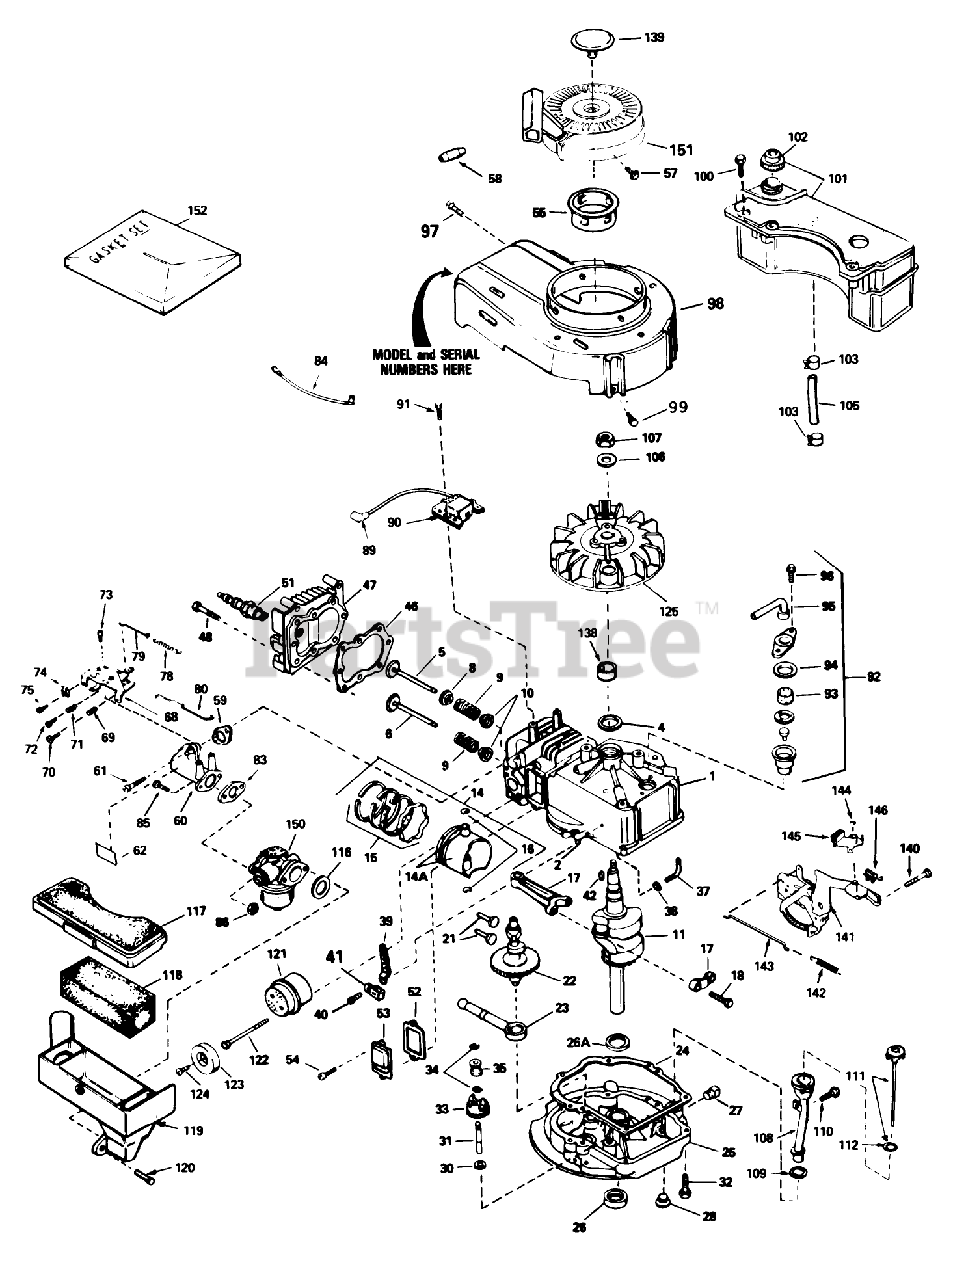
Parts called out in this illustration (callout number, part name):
1	Cylinder Assy. (Incl. #24)
2	Pin-Dowel
4	Seal-Oil
5	Valve, Intake (Std.) (Incl. Ref. #40)
5	Valve, Intake (1/32" oversize)(Incl. No. 40)
6	Valve, Exhaust (Std.)(Incl. No. 40)
6	Valve, Intake (1/32" oversize)(Incl. No. 40)
8	Seal Assy., Intake
9	Spring-Valve
10	Cap-Valve, Spring
11	Crankshaft
14	Piston, Pin Ring Assy. (Std.) (Incl. Ref. #13A, 14 15)
14	Piston, Pin Ring Assy. (.010 oversize) (Incl. Ref. #13A, 14 15)
14	Piston, Pin Ring Assy. (.020 oversize) (Incl. Ref. #13A, 14 15)
14A	Piston Pin Assy. (Incl . Ref. . #14) (Std.)
14A	Piston Pin Assy. (Incl. Ref. #14) (.010 Oversize)
14A	Piston Pin Assy. (.020 oversize) (Incl. Ref. #14)
15	Ring Set (Std.)
15	Ring Set (.020" OS)
15	Ring Set (.010" OS)
16	Ring-Retaining, Piston Pin
17	Rod Assy., Connecting (Incl. Ref. #17)
18	Bolt-Rod, Connecting
21	Lifter-Valve
22	Camshaft(Mech.Comp. Release)
23	Oil Pump ASM
24	Gasket
25	Flange-Mounting (Incl. Ref. #26, 27 39)
26	Seal-Oil
26A	Washer-Thrust
28	Plug Oil Drain
30	Washer-Flat
31	Shaft-Governor
32	Screw (1/4-20 x 1-1/4)
33	Governor Gear ASM
34	Ring-Retaining
35	Spool-Governor
37	Rod, Governor (Incl. No. 36)
38	Washer-Flat
39	Governor Lever
40	Screw
41	Clamp-Lever, Governor
42	Key-Flywheel
46	63573 GIL 42 SNWTHW
47	Head-Cylinder
48	Screw (5/16-18x1-1/2)
51	Plug, Spark (Autolite 458, Champion J-19LM or equiv.)
52	Gasket-Breather
53	Cover-Valve
54	Screw
55	Hub-Starter
57	Screw, Hex Hd.
58	Retainer-Starter Rope
59	Gasket-Intake
60	Pipe-Intake (Incl. Ref. #59)
61	Screw (1/4-20 x 1)
62	Decal-Primer
68	Control Assy.-Remote Speed (Incl. Ref. #69 thru 72 76)
69	61709/GIL1515A/95-5
70	Screw
71	Spring-Compression
72	Screw
73	Screw (10-24 x 9/16)
74	Conduit
75	Screw (10-32 x 3/8)
78	Spring Governor
79	2035A67 ADD.ASSEMBL
80	Link-Throttle
83	Gasket
84	Ground Wire
86	Nut and Lock Washer (1/4-28)
89	Cover-Spark Plug
90	Solid State
91	Screw
92	Breather Assy. (Incl. Ref. #46 thru 51)
93	Element-Breather
94	Gasket-Breather
95	Tube, Breaker
96	Screw (10-24 x 9/16)
97	Screw (10-24 x 9/16)
98	Housing-Blower
99	Screw (1/4-20 x 1/2)
100	Screw (10-32 x 35/64)
101	Tank Assembly-Fuel (Incl. Ref. #102)
102	Cap-Fuel
103	Clamp-Line, Fuel
105	Line-Fuel
106	Washer-Belleville
107	Nut-Flywheel
108	Tube-Oil Fill
109	Gasket
110	Screw (10-32 x 1/2)
111	Dipstick-Oil (Incl. Ref. #112)
112	O-Ring
116	Gasket-Cleaner, Air
117	Cover-Air Cleaner
118	Filter-Air Cleaner
119	Body Air cleaner
120	Screw
121	Muffler (Incl. Ref. #122)
122	Screw
123	Cover-Muffler
124	Screw (8-32 x 3/8)
125	Flywheel
138	Spacer
139	Plug Starter
140	Screw (1/4-20 x 3/8)
141	Bracket-S.E. Brake
142	Spring-Extension
143	Link-Control
144	Ring-Retaining
145	Lever-Brake
146	Terminal
150	Carburetor (Incl. Ref. #83)
151	Starter-Rewind
152	Gasket Set
